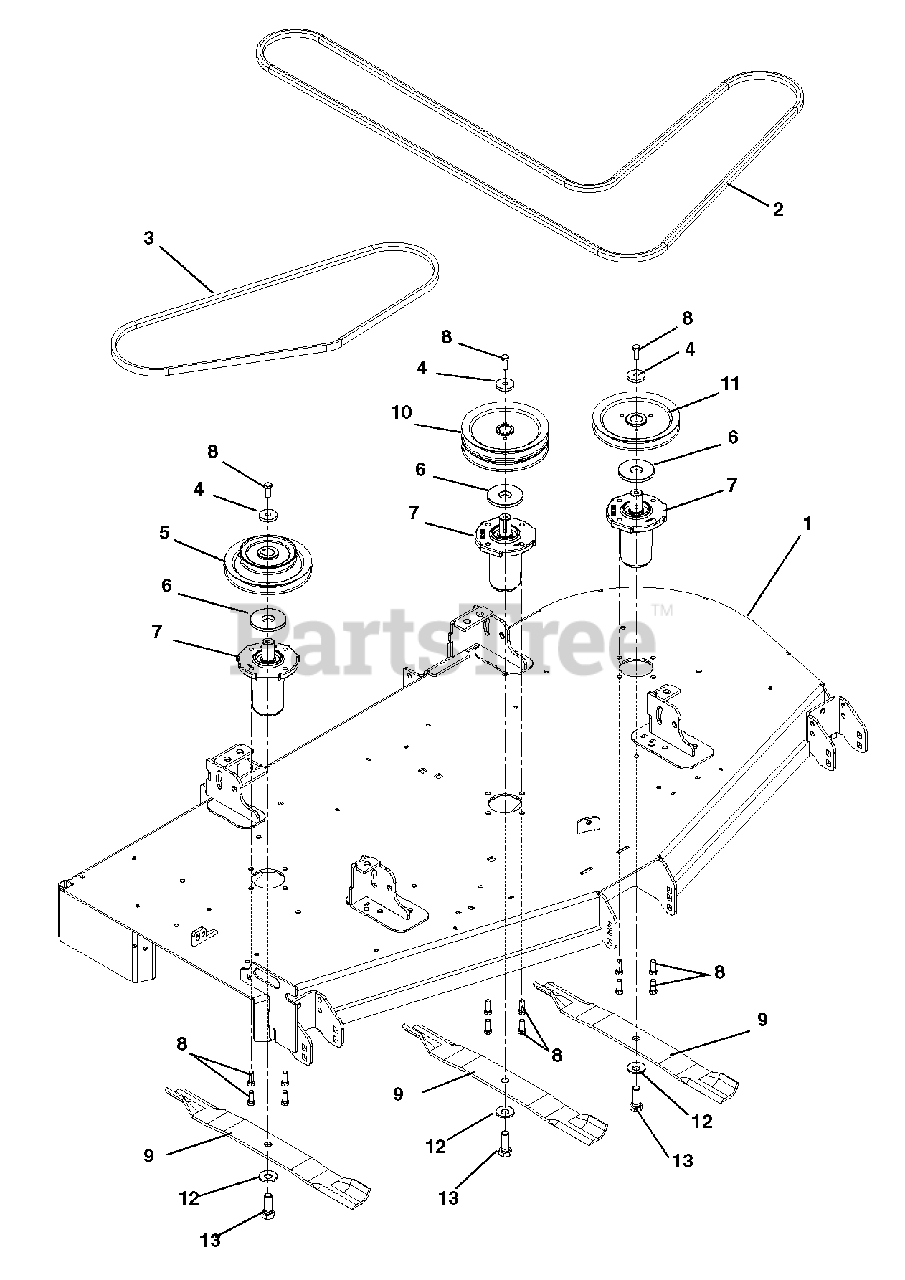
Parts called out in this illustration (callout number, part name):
1	Weldment, 52" PT200 CE Side Discharge
2	Hex Belt, BB-Wrapped
3	V-Belt, B-Cogged
4	Washer, Flat Steel .406 x 1.50 x .245
5	Sheave,1" ID x 6.00" OD and 3.50" OD
6	Retainer, Grease
7	Assembly, Spindle G3500
8	Bolt, Hex .38-16 x 1.00
9	Blade, Mulch (18.00")
10	Pulley, Double
11	Pulley, Single 1"ID x 6.00" OD
12	Washer, Bellville .63 x 1.625 x .14
13	Bolt, Hex .62-18 x 1.75 Grade 8
